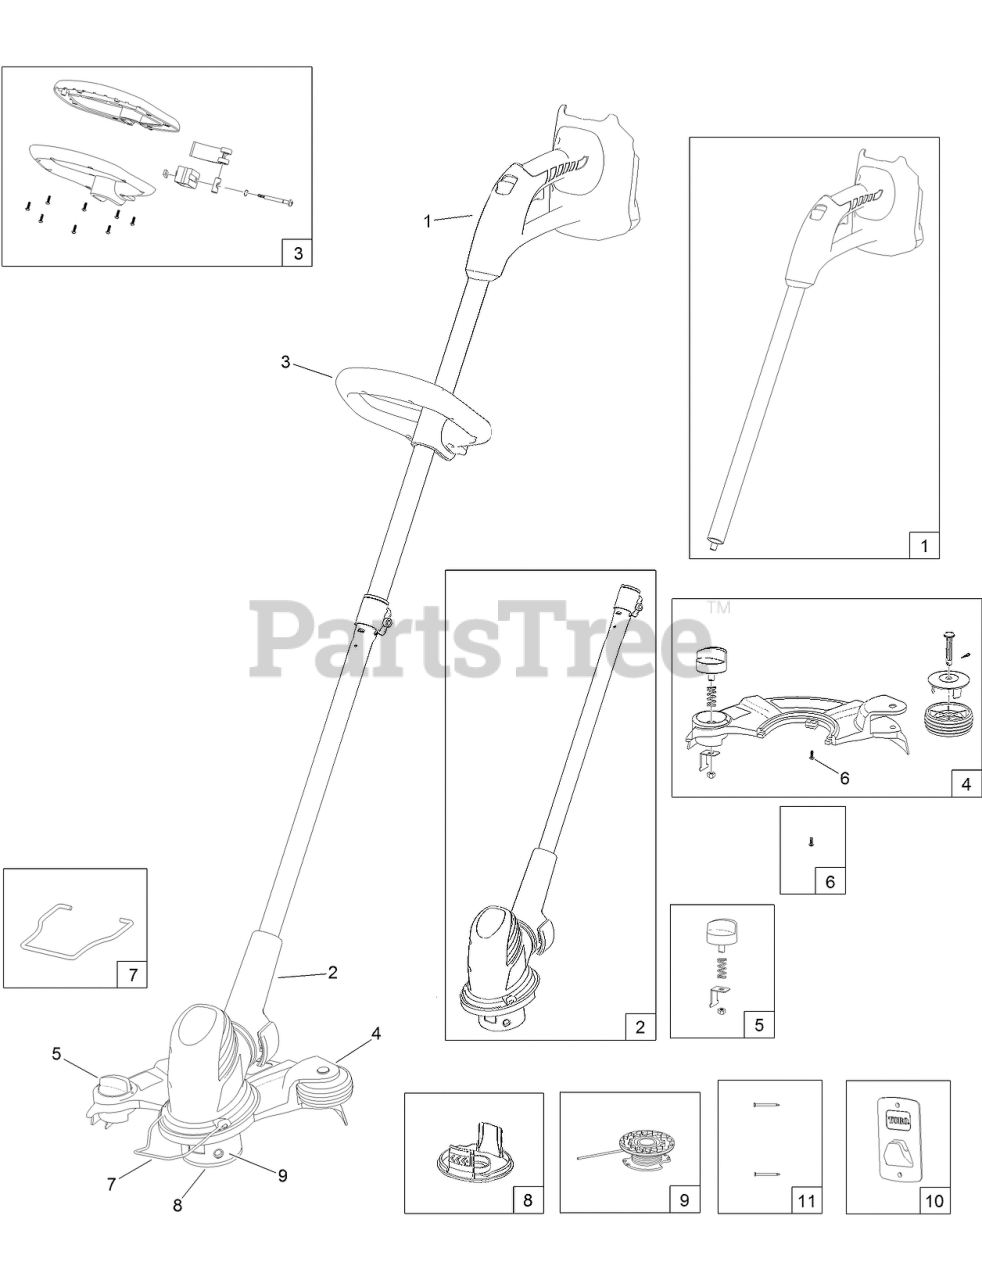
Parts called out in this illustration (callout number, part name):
1	HANDLE-UPPER
2	LOWER MOTOR HOUSING ASM
3	ASSIST HANDLE ASM
4	GRASS SHIELD ASM
5	KNOB-SAVER, POWER
7	CLIP-GUIDE, EDGER
8	CAP-RETAINER, SPOOL
9	SPOOL-TRIMMER, 12 INCH
10	BRACKET-MOUNT, WALL
